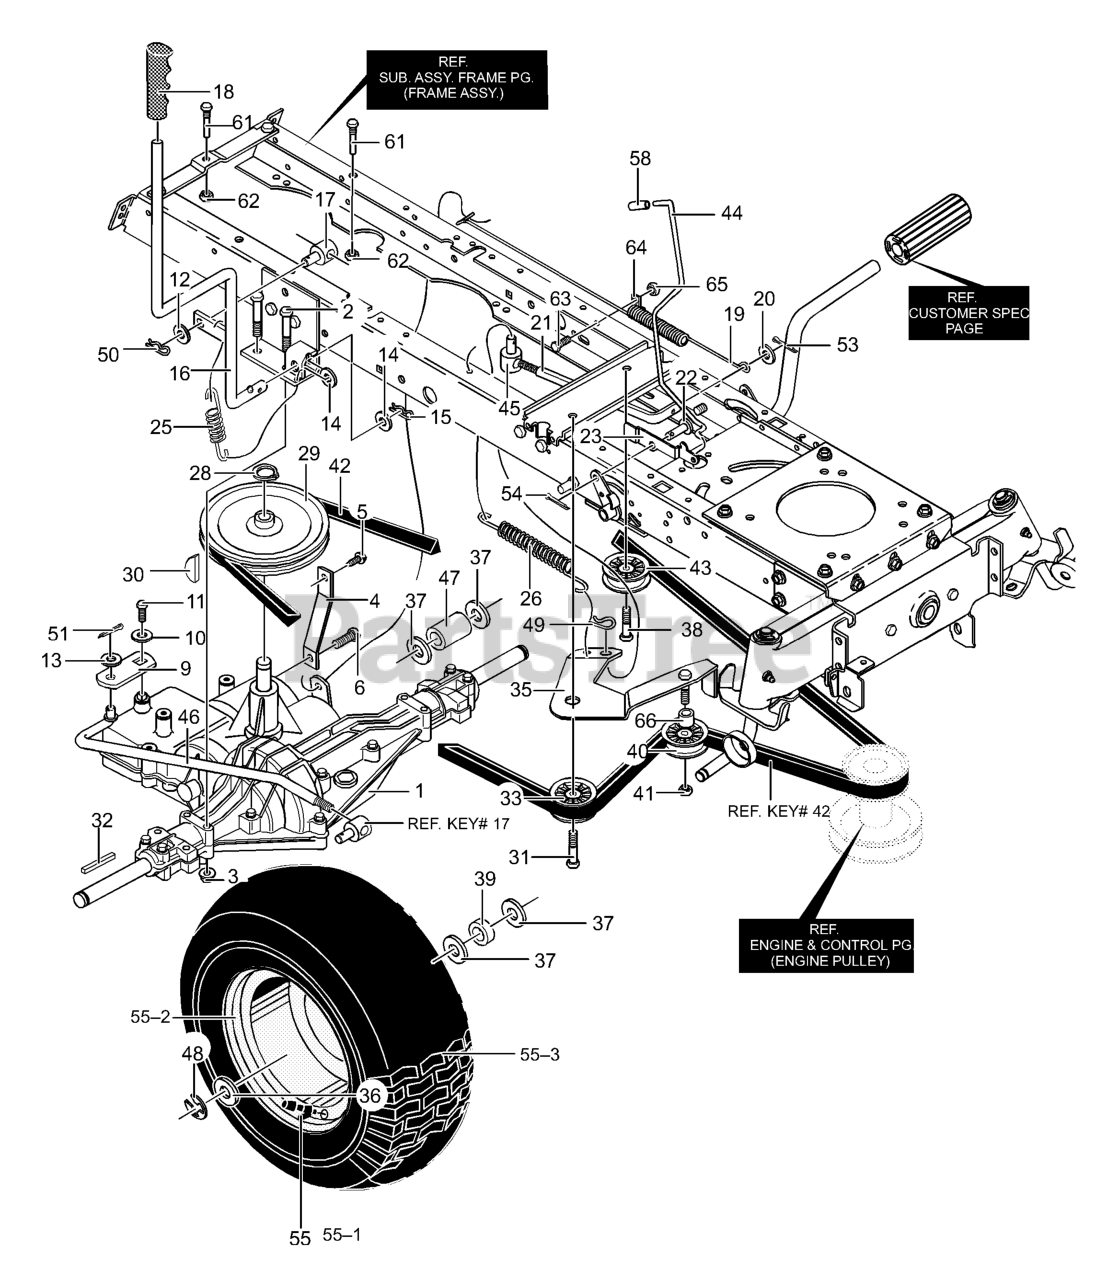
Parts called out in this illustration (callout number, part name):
1	Transaxle, MST206 **
2	Screw, 5/16-18 x 2.50
3	Nut, 5/16-18
4	Bracket, Stabilizer
5	Screw, 5/16-18 x 0.75
6	Screw, 5/16-18 x 0.75
9	Bracket, Shift
10	Washer, Transaxle
11	Screw, 1/4-28x.750
12	Washer, Flat
13	Washer
14	Flatwasher
15	Hair Pin
16	Shift Lever
17	Nut, Adjust
18	Grip
19	Spring, Brake
20	Washer, Flat
21	Rod, Clutch
22	Pin, Clevis
23	Latch, Park Brake
26	Spring, Tension
28	Ring, Ret
29	Pulley, 9.0 ODV4L
30	Key, Hi Pro 606
31	Screw, 3/8-16 x 1.25
32	Key, Square
33	Pulley, Idler
35	Assy, Idler Arm Traction
36	Washer, Flat
37	Washer, Flat
38	Screw, 3/8-16 x 1.25
40	Pulley, Idler
41	Nut, 3/8-16
42	Belt, V 4L 114.12
43	Pulley, Idler
44	Park Brake Control Rod
45	Nut, 5/16-18 Adjusting
46	Rod, Shift Link
47	Spacer
49	Pin, Hair
50	Pin, Hair
51	Pin, Cotter
53	Pin, Cotter
54	Pin, Cotter
55	Tire & Rim
55-1	Valve Stem
58	Cap, Dump
61	Screw Guide
62	Nut, 1/4-20
63	Screw, 1/4-20x.50
64	Retainer
65	Nut, 1/4-20
66	Spacer 1/2 to 17MM
